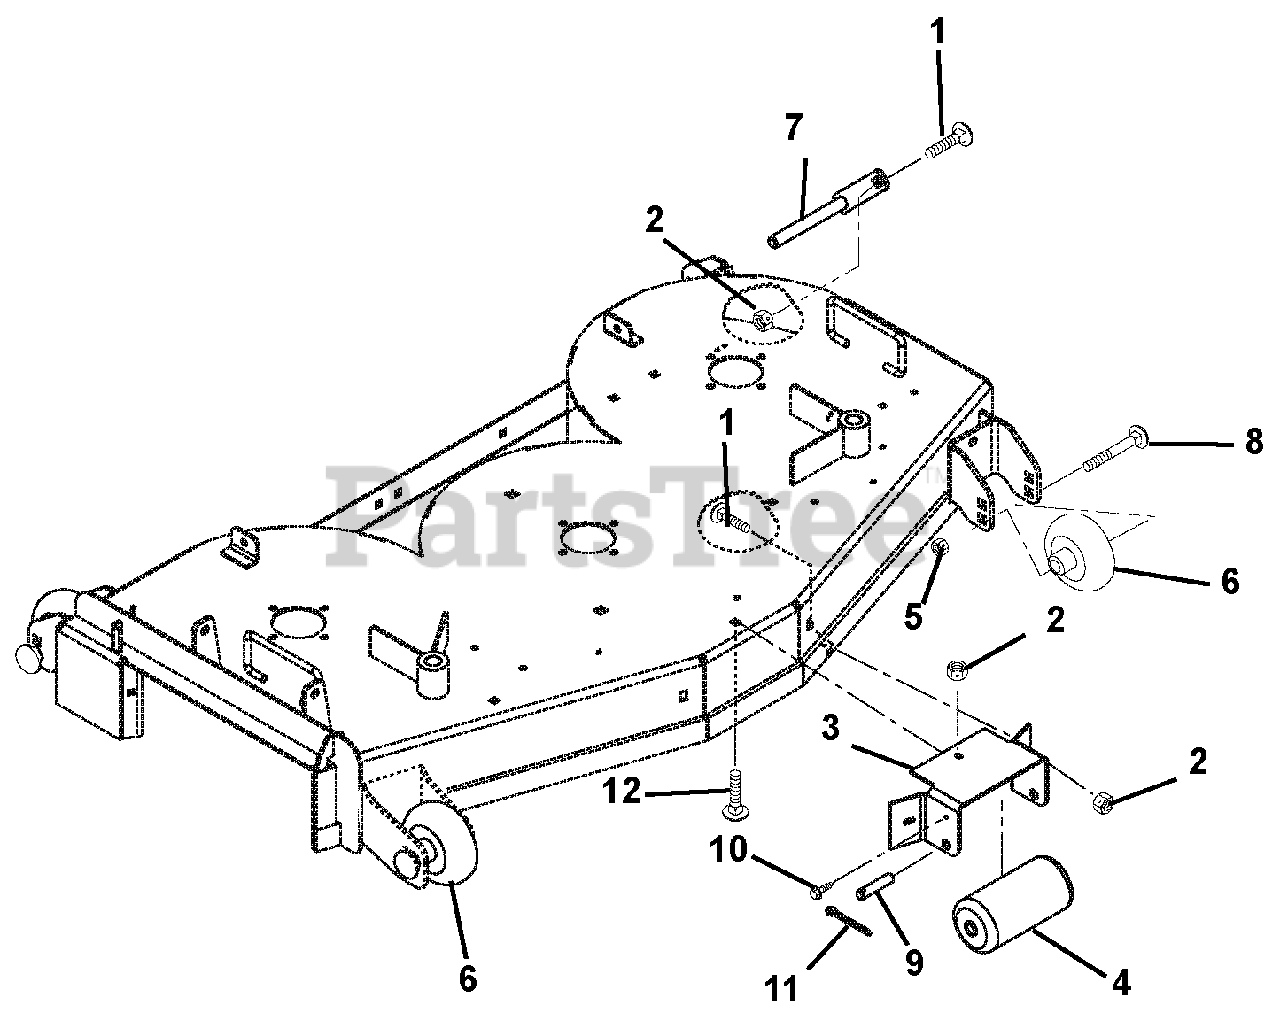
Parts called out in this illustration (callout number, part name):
1	Bolt, Round Head Square Neck .38-16 x 1.00 Grade 5
2	Nut, Locking-Top-Flange .38-16
3	Bracket, Anti-Scalp Roller
5	Nut, Locking-Top-Flange .50-13
6	Wheel, 3 x 5
7	Weldment- Wheel Retainer
8	Bolt, Round Head Square Neck .50-13 x 4.50 Grade 2
10	Screw, Tapping .25-20 x .50 Hex Washer Head
11	Pin, Cotter .25 x 2.00
12	Bolt, Round Head Square Neck .38-16 x .75 Grade 5
